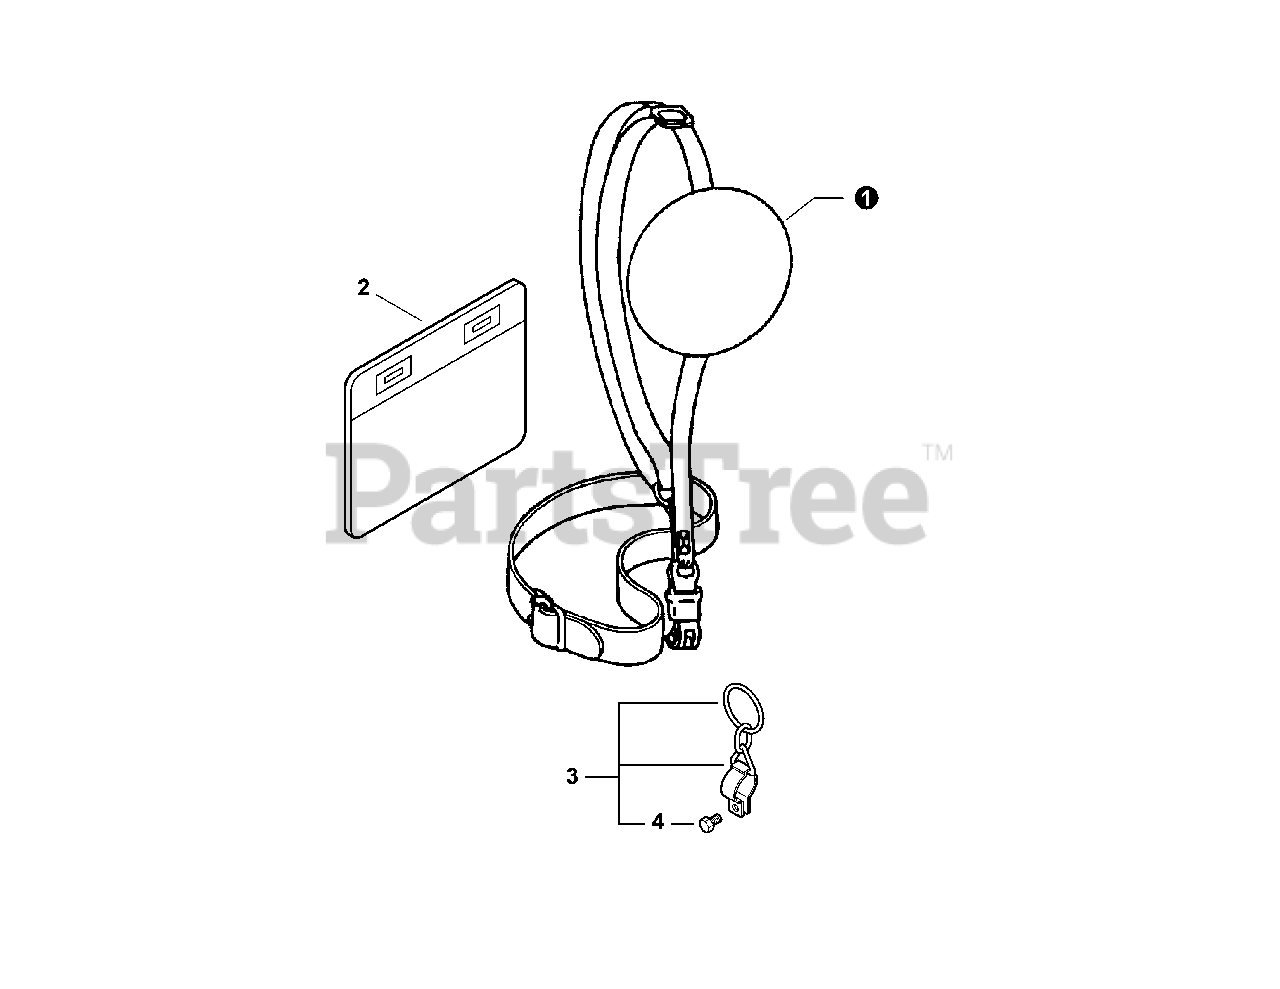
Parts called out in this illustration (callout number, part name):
1	HARNESS, SHOULDER
2	PAD, HIP
3	HANGER SET, HARNESS
4	BOLT, TORX 5×12
